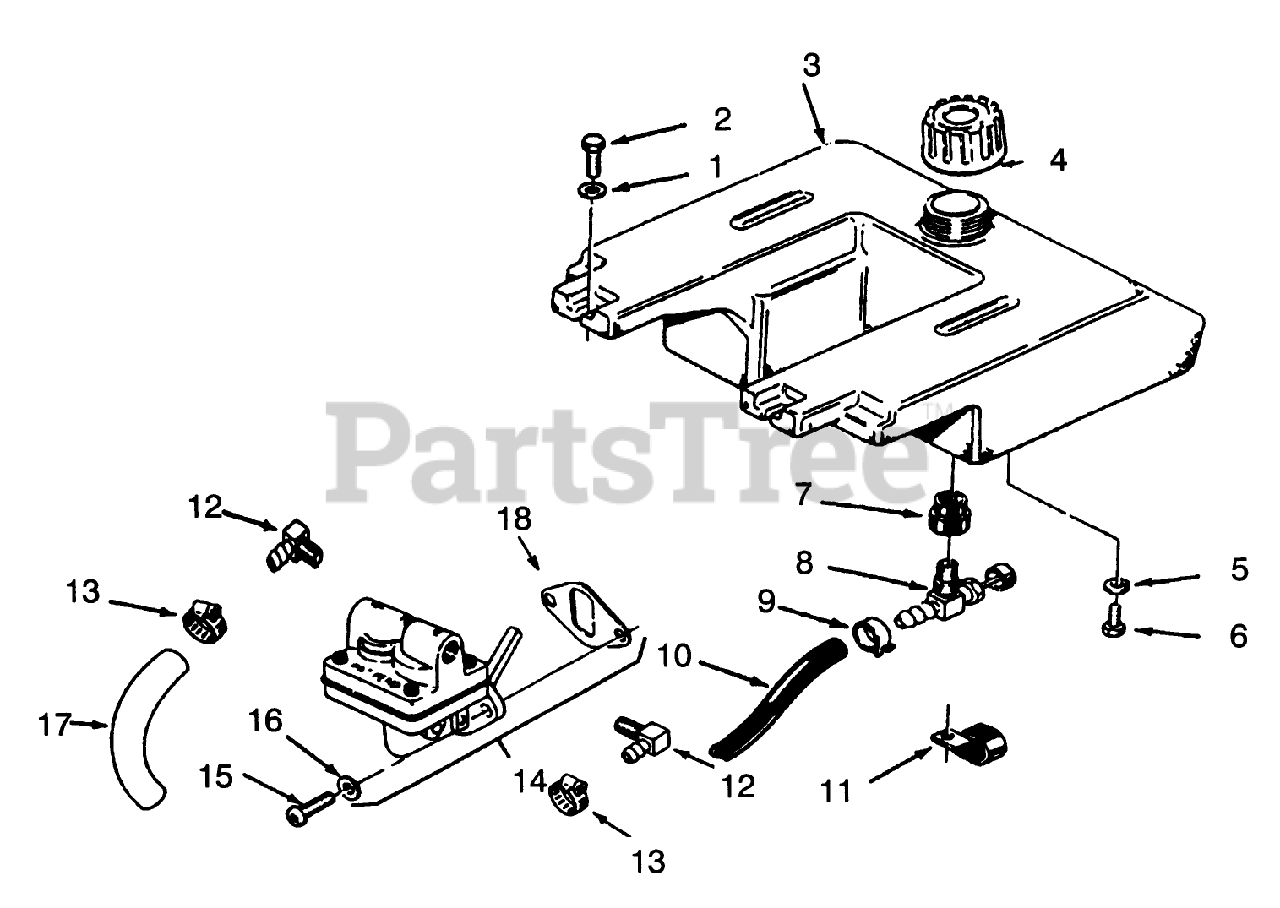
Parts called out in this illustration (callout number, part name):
1	WASHER-FLAT
3	TANK-FUEL
4	GAS CAP ASM
5	WASHER-LOCK
6	SCREW-HH
8	VALVE-FUEL
12	KOHLER 25-155-02
13	KOHLER X-426-9
14	KOHLER 47-559-08
15	KOHLER X-174-2
16	KOHLER X-25-63
17	KOHLER 25-353-01
18	KOHLER 25-041-05
